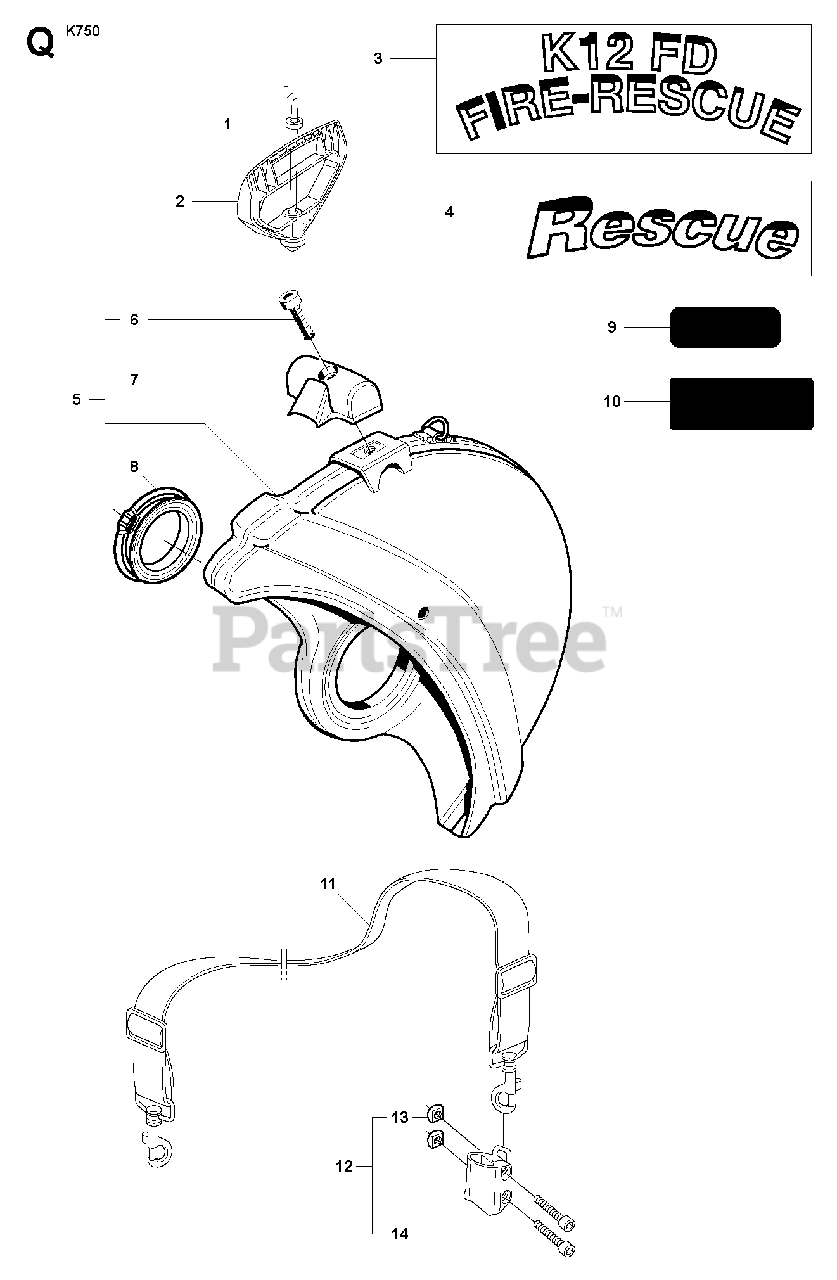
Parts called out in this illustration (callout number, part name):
2	STARTER HANDLE
5	BLADE GUARD"Rescue 12"". Incl. 6 - 8"
6	SCREW IHSCM
11	SHOULDER STRAP
12	BRACKET"Rescue 12"". Incl. 6 - 8"
14	SCREW ITXSCM
